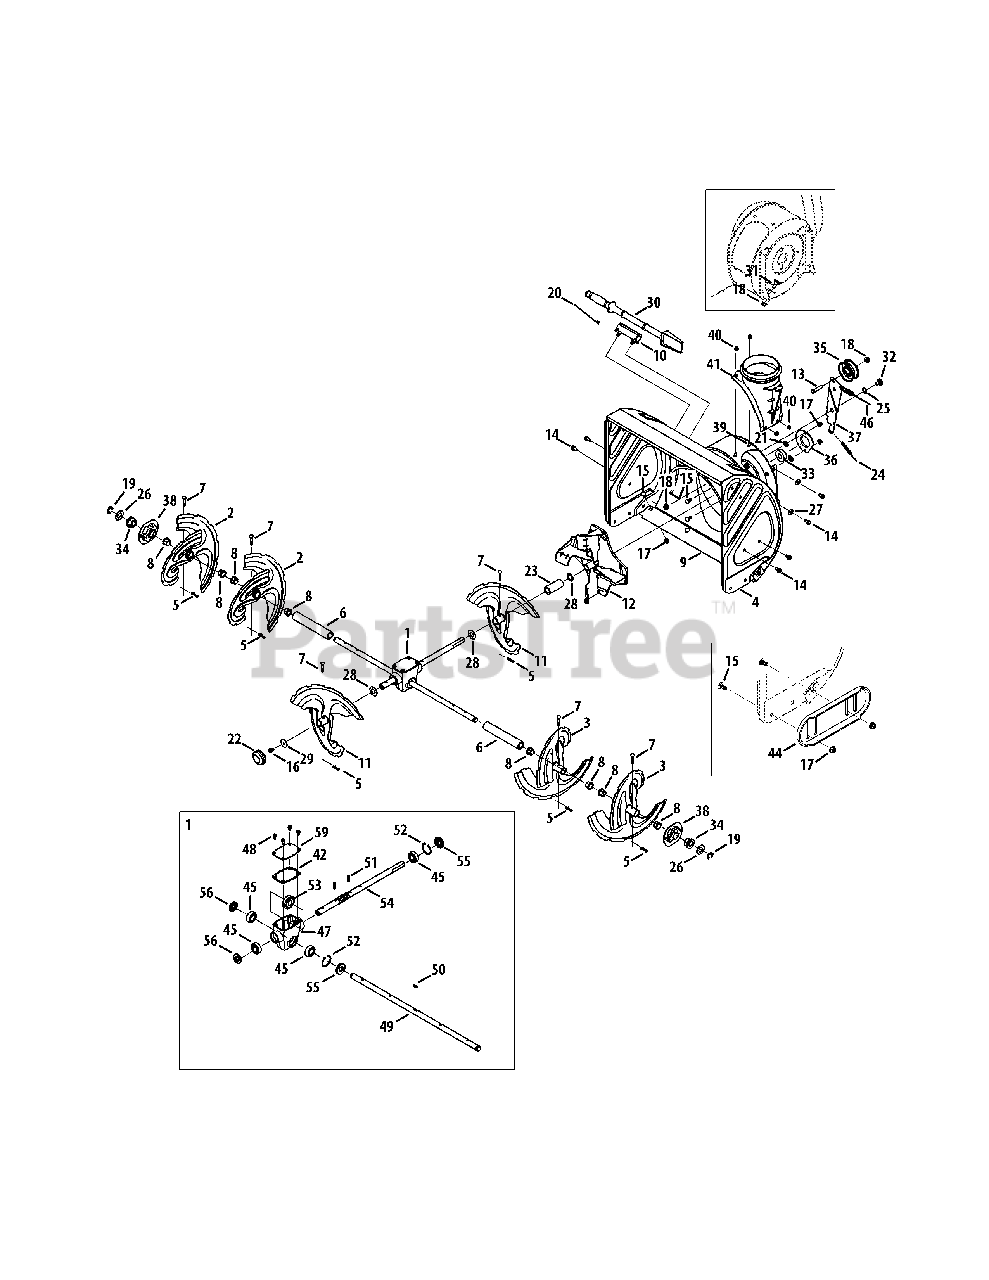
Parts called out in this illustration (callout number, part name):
1	Gearbox Assembly, Auger, 30"
2	Spiral Assembly - RH
3	Spiral Assembly - LH
4	Auger Housing, 30"
5	Bow Tie Cotter Pin
6	Spacer, 1.25 OD x .75 ID x 7.38
8	Flange Bushing, .800 x .910
9	Shave Plate, 30"
10	Clean-out Tool Mtg. Bracket
11	Accelerator Assembly
12	Impeller Assembly
13	Hex Bolt, 3/8-16 x 1.75
14	Screw, 5/16-18 x .750
15	Carriage Bolt, 5/16-18 x .750
16	Hex Washer Screw, 5/16-18 x .500
17	Flange Lock Nut, 5/16-18
18	Flange Lock Nut, 3/8-16
19	E-ring, .75
20	Cable Tie
21	Push-On Nut, .25 Dia.
23	Spacer, 1.35 OD x .76 ID x 2.705
24	Extension Spring, .38 OD x 4.59
25	Wave Washer, .625 x .885 x .0175
26	Flat Washer, .76 x 1.49 x .06
27	Bell Washer, .340 x .872 x .060
28	Flat Washer, .793 x 1.24 x .06
29	Flat Washer, .406 x 1.92 x .060
30	Clean-Out Tool
31	Shoulder Screw, 3/8-16 x .496 x .336
32	Shoulder Screw, 3/8-16 x .625 x .17
33	Flange Ball Bearing, .75 x 1.85
34	Hex Flange Bearing, .75 ID
35	Flat Idler Pulley
36	Bearing Housing
37	Auger Idler Bracket
38	Bearing Housing
39	Carriage Screw, 1/4-20 x 0.75
40	Flange Lock Nut, 1/4-20
41	Chute Adapter
42	Gearbox Gasket
43	Gearbox Cover
44	Deluxe Slide Shoe
45	Ball Bearing, .75 x 40 x 12
46	Auger Clutch Cable
47	Auger Housing
48	Screw, 1/4-20 x 0.75
49	Axle, Auger, 30"
50	Hi-Pro Key
51	Pin, Roll, .25 x 1.0
52	Retainer Ring
53	Worm Gear, 20T
55	Seal, .75 x 40mm x .25
56	Seal, .75 x 1.375 x .25
